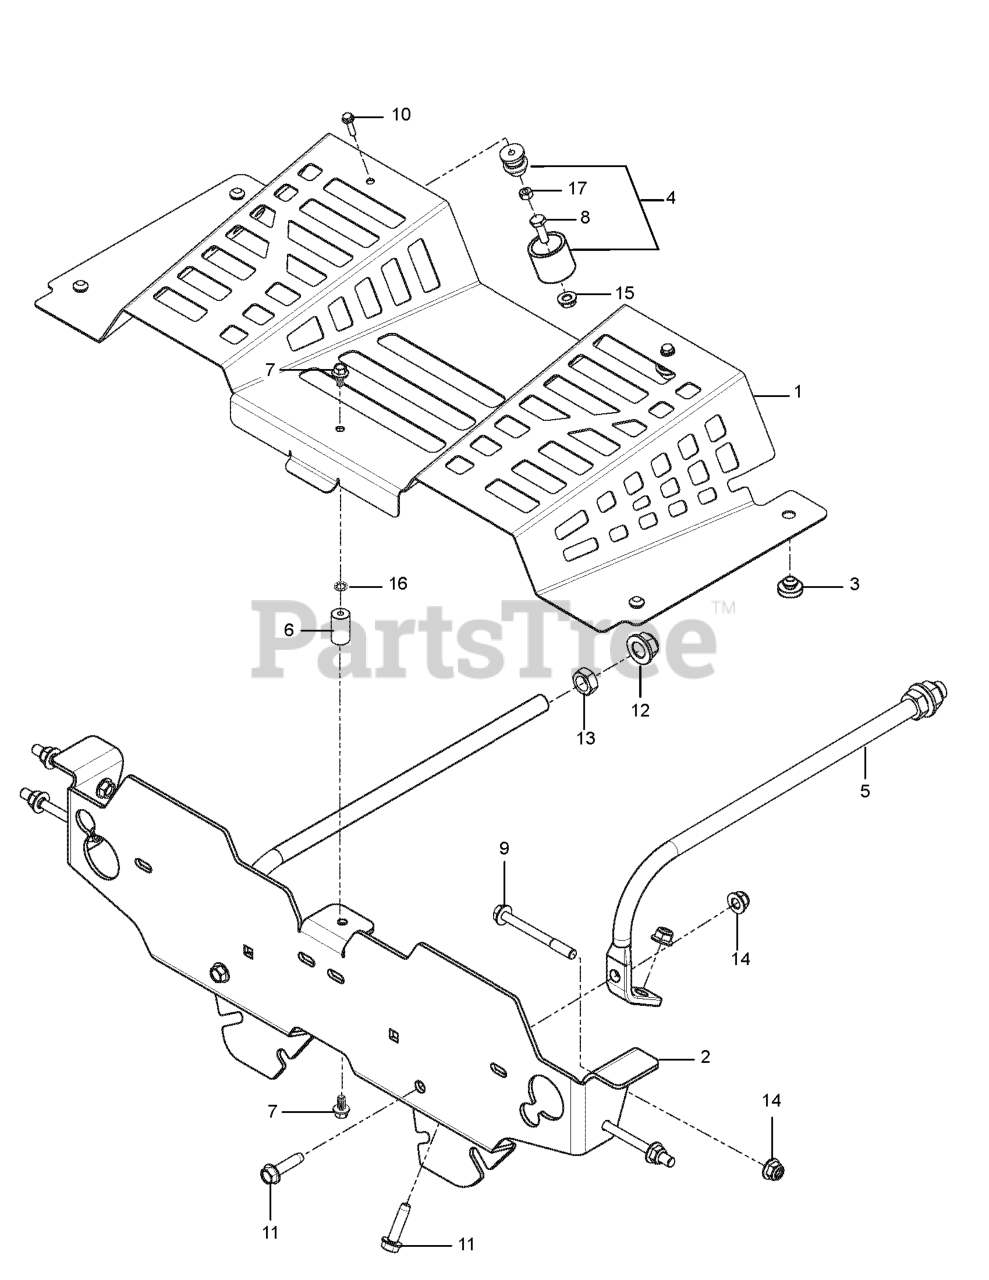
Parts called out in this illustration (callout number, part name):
1	SHIELD FAN GROMMET BLACK X431
2	BRACKET ANCHOR CABLE ORANGE X6
3	GROMMET, BUMPER
4	HOLDER.ASM.STEM.BASE.WASHER
5	ROD.CROSS.MEMBER.ANVH.CAB.YZIN
6	SPACER TUBE 1/4 - 20
7	SCREW
8	BOLT
9	BOLT HEX FLGHD 5/16-18X3 GR. 5
10	SCREW M6SF 5X20
11	SCREW.THDROL.5/16-18X1.25.TYTT
12	NUT, 1/2-13 HEX FLG NYLOC ZD
13	NUT.HEX.JAM.1/2-13
14	5/16-18 NYLOC FLANGE NUT
15	NUT.FLG.NYLOCK.1/4-20.GR.G.ZY
16	PALNUT 1/4
17	NUT M6M M5
